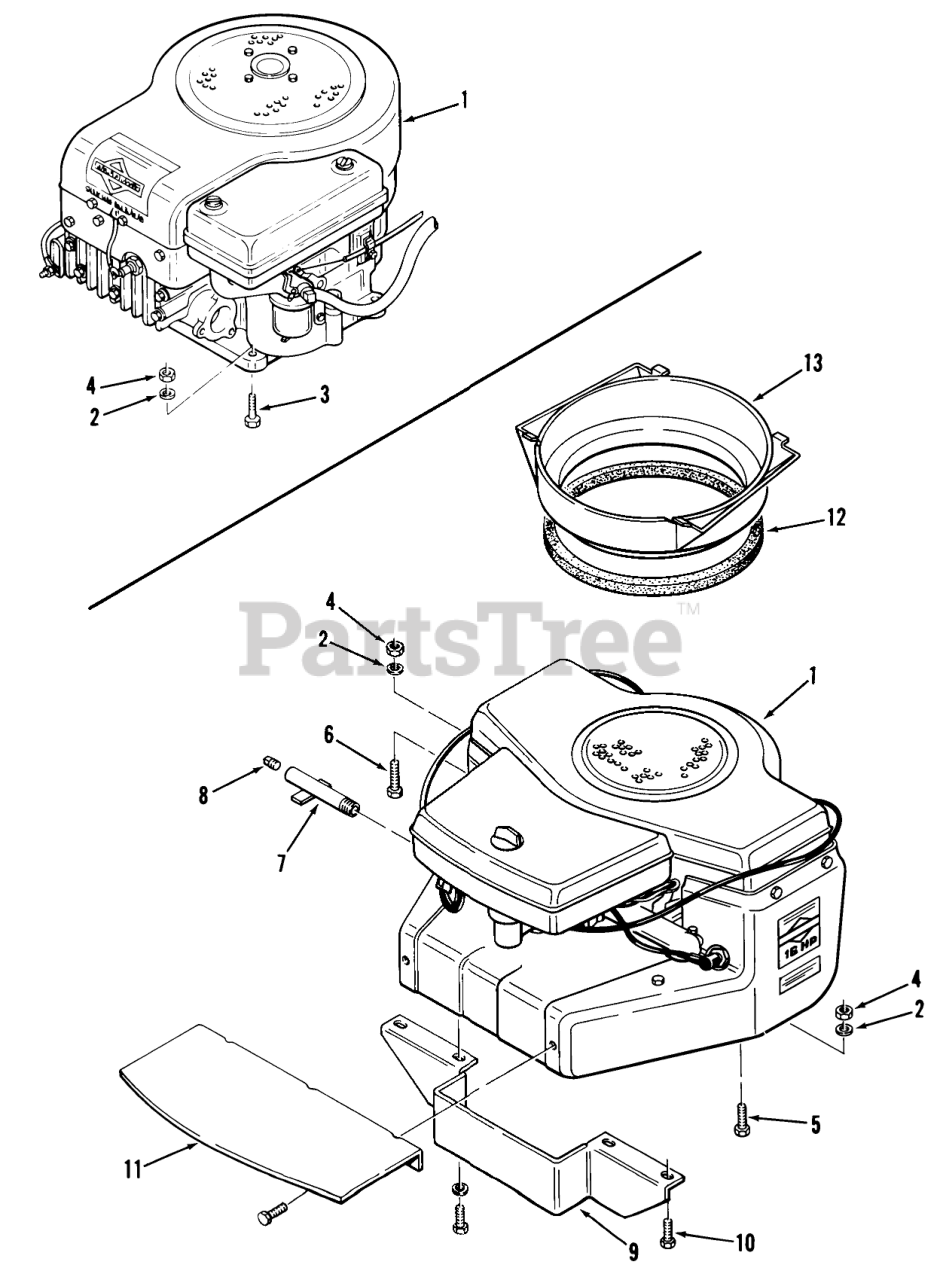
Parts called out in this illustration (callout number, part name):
1	Engine-8HP-BS Model 191707, Type 1136-01
1	Engine-11HP-BS Model 252707, Type 0206-01
1	Engine-11HP-BS Model 252707, Type 0209-01
1	Engine-16HP-BS Model 401707, Type 0111-04
2	WASHER 5/16 SAE
13	Duct-Hood Air Intake B-165 Only
